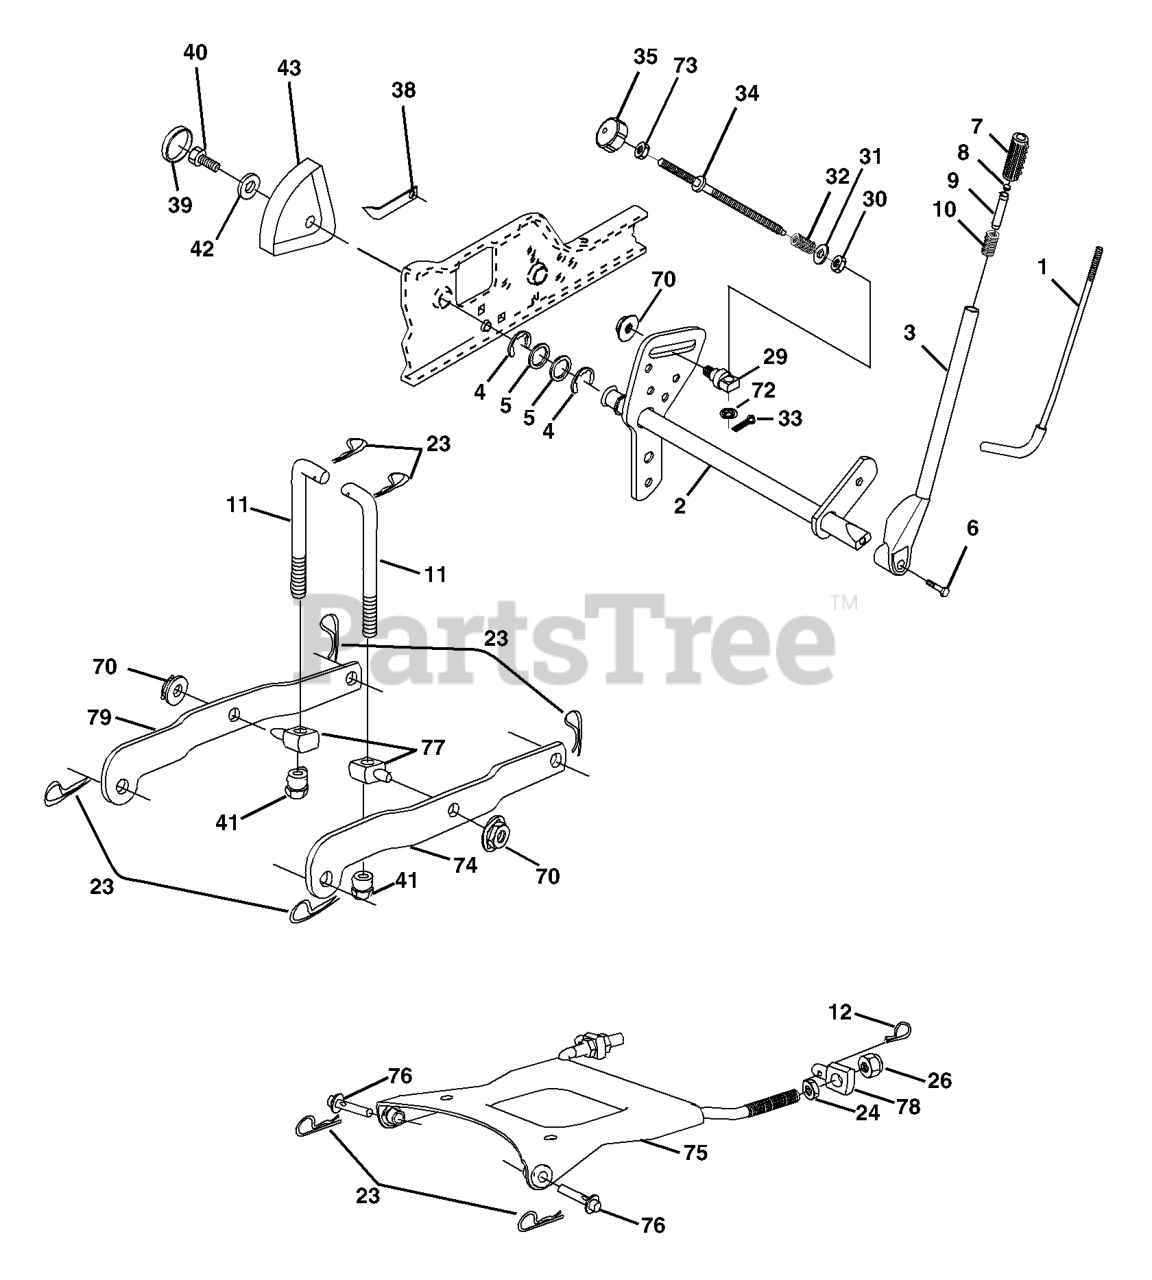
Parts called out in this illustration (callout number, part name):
1	LEVER ROD LT
2	SHAFT ASM., LIFT VGT
3	LEVER ASSY-LIFT RH
5	Washer 29/32 x 1-1/4 x 16 Ga.
6	Bolt, Fin Hex 3/8-16 x 1-1/2
7	GRIP HANDLE
8	PLUNGER BUT KIT
9	PLUNGER BUT KIT
10	SPRING 0.620D X 2.125
11	LIFT LINK
12	SPRING RETAINER
23	RETAINER-SPRNG RB
24	NUT.HEX.JAM.1/2-13
26	NUT.LK.W/WSH.1/2.
32	SPRING.COMP.INF.H
33	COTTER PIN
34	ROD.LIFT.ADJUSTABLE
35	KNOB INF 3/8-16
38	POINTER, HEIGHT INDICATOR(2 2)
40	SCREW 5/16-18X1
41	NUT, LIFT LINK 7/16-20
43	HEIGHT INDICATOR
70	NUT
72	NUT PUSH M
73	NUT
74	ARM SUSP REAR RH
75	PLATE ASM SUSP FRONT
76	PIN.FLANGE
79	ARM SUSP. REAR LH
